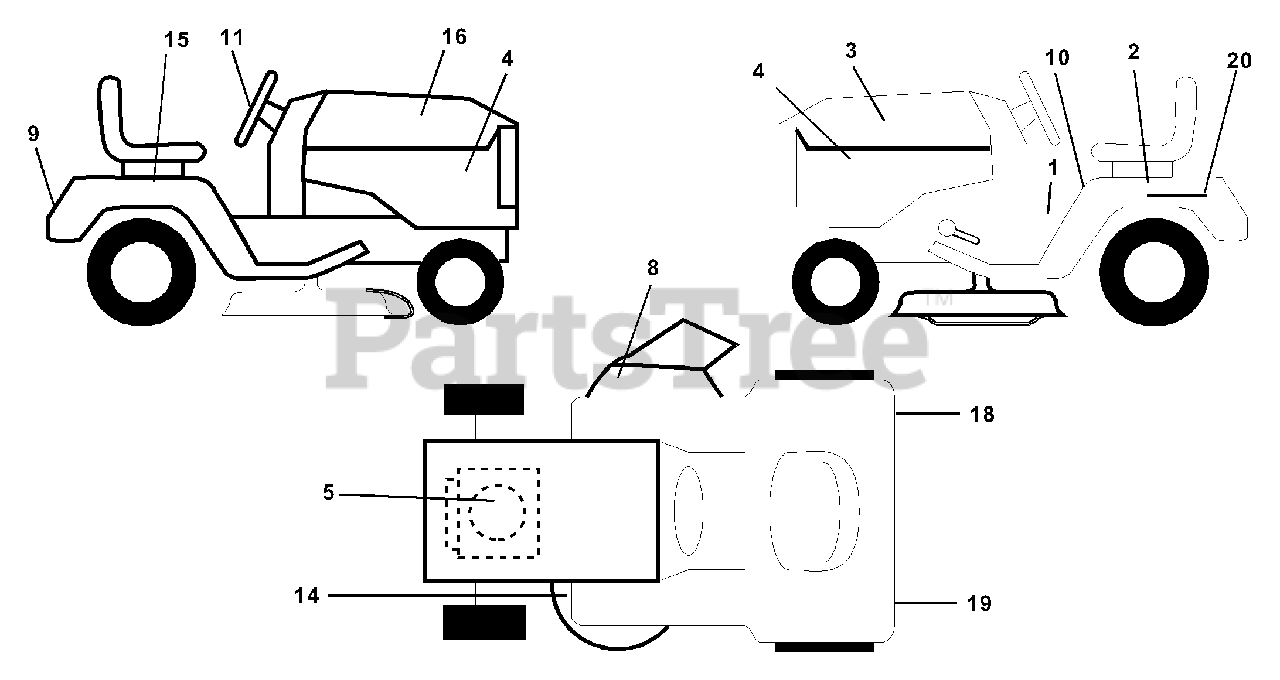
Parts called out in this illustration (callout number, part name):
2	Decal Fender Side Lh
3	Decal Hood LH
4	Decal Side Panel Logo
5	Decal HP Engine
8	Decal Warning Mult-Language
9	Decal Fender Logo
10	Decal Fender Danger E/F
11	Decal Ins Strg Whl
14	Decal V-Belt Schematic
16	Decal Hood Rh
18	Decal Fender Reflector RH
19	Decal Fender Reflector LH
20	Decal Bat Dan/Psn
